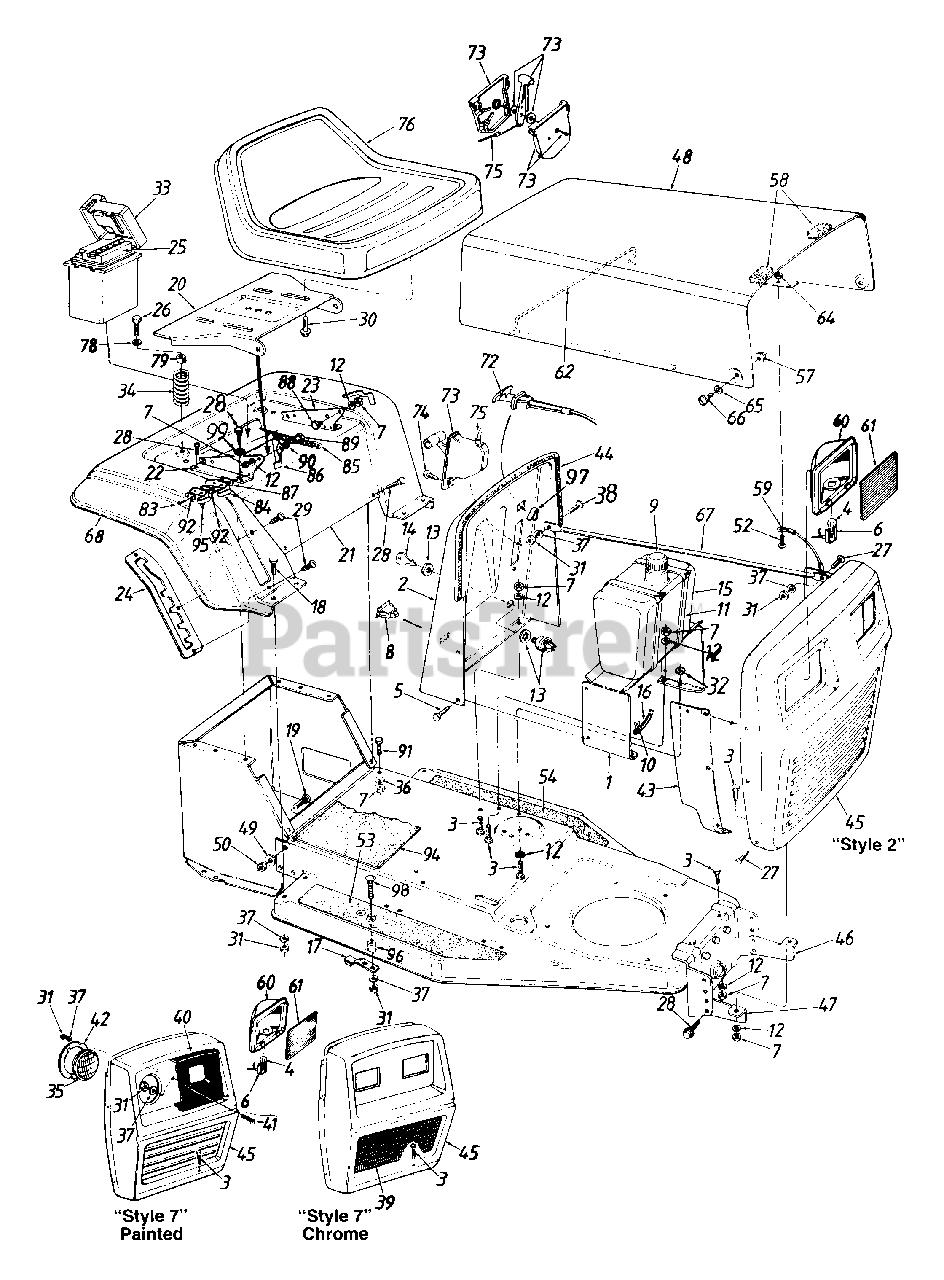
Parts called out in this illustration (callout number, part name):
1	Dash Panel Support Brkt.
4	Bulb
5	Hex AB-Tap Scr. 1/4 x .62"
6	Socket
7	Hex Nut 5/16-18 Thd.
8	Light Switch
9	Gas Cap
10	Hose Clamp
11	Cable Tie
12	L-Wash. 5/16" I.D.
13	Ignition Switch
14	Ignition Key
15	Fuel Tank
16	Gas Line 15" Long
17	Blade Brake Ass'y.
18	Carriage Bolt 1/4-20 x .62"
19	Ribbed Neck Bolt 3/8-24 x .8"
20	Seat Pivot Brkt.
25	Battery
26	Hex Self-Tap Screw 5/6-18 x 1.25" Lg.
27	Truss Mach. Scr. 1/4-20 x .75" Lg.
28	Hex AB-Tap Scr. 5/16 x .75" Lg.
29	Torx Mach. AB-Tap Scr. 1/4 x 62" Lg.
30	Hex Self-Tap Scr. 3/8-16 x 62" Lg. 75" Lg.
31	Hex Nut 1/4-20 Thd.
32	Hex Jam Nut 5/16-18 Thd.
33	Battery Box w/Cover
34	Compression Spring
35	Headlight (Style 7)
36	Bell-Wash. 5/16" I.D.
37	L-Wash. 1/4" I.D.
38	Hex Bolt 1/4-20 x .62" Lg.
39	Grille insert
40	Bezel
41	C-Sunk Mach. Scr. 1/4-20 x 1.5"
42	Headlight Retainer
44	Trim Strip 31" Lg.
47	Grille Mtg. Brkt.- R.H.
50	Hex L-Nut 3/8-24 Thd.
52	Truss Mach. Scr. #10-24 x .5" Lg.
53	Foot Pad - R.H.
54	Foot Pad - L.H.
57	Lock Nut 1/4-28 Thd.
58	Foam Strip
59	Hood Stop
60	Headlight Housing
61	Lens
62	Hood Spring
64	Hex Sems Nut #10-24 Thd.
65	Spr. Wash..39" I.D. x .62" O.D.
66	Shld. Bolt
72	Choke Control
73	Throttle Control Box
74	Truss AB-Tap Scr. #10 x .5"
75	Throttle Wire (B&S)
76	Seat Assembly
78	Fl-Wash..344" I.D. x .88" O.D.
79	Bushing
83	Hex Tap Scr. #8 x .5" Lg.
84	Safety Switch (Seat)
85	Ext. Spring 5.31" Lg.
86	Seat Lift Brkt.
87	Insulator Boss Plate
88	Shld. Bolt .437" Dia. x .162" Lg.
89	Shld. Bolt .437" Dia. x .268" Lg.
90	Spr. Wash..445" I.D. x .75" O.D.
91	Hex Wash. Hd. Scr. 5/16-18 x .62" Lg.
92	Insulator Plate
94	Center Foot Pad
95	Safety Switch (Seat)
96	Spacer
97	Retainer Clip
98	Carriage Bolt 1/4-20 x 1.25" Lg.
99	Ext. L-Wash. 5/16" I.D.
